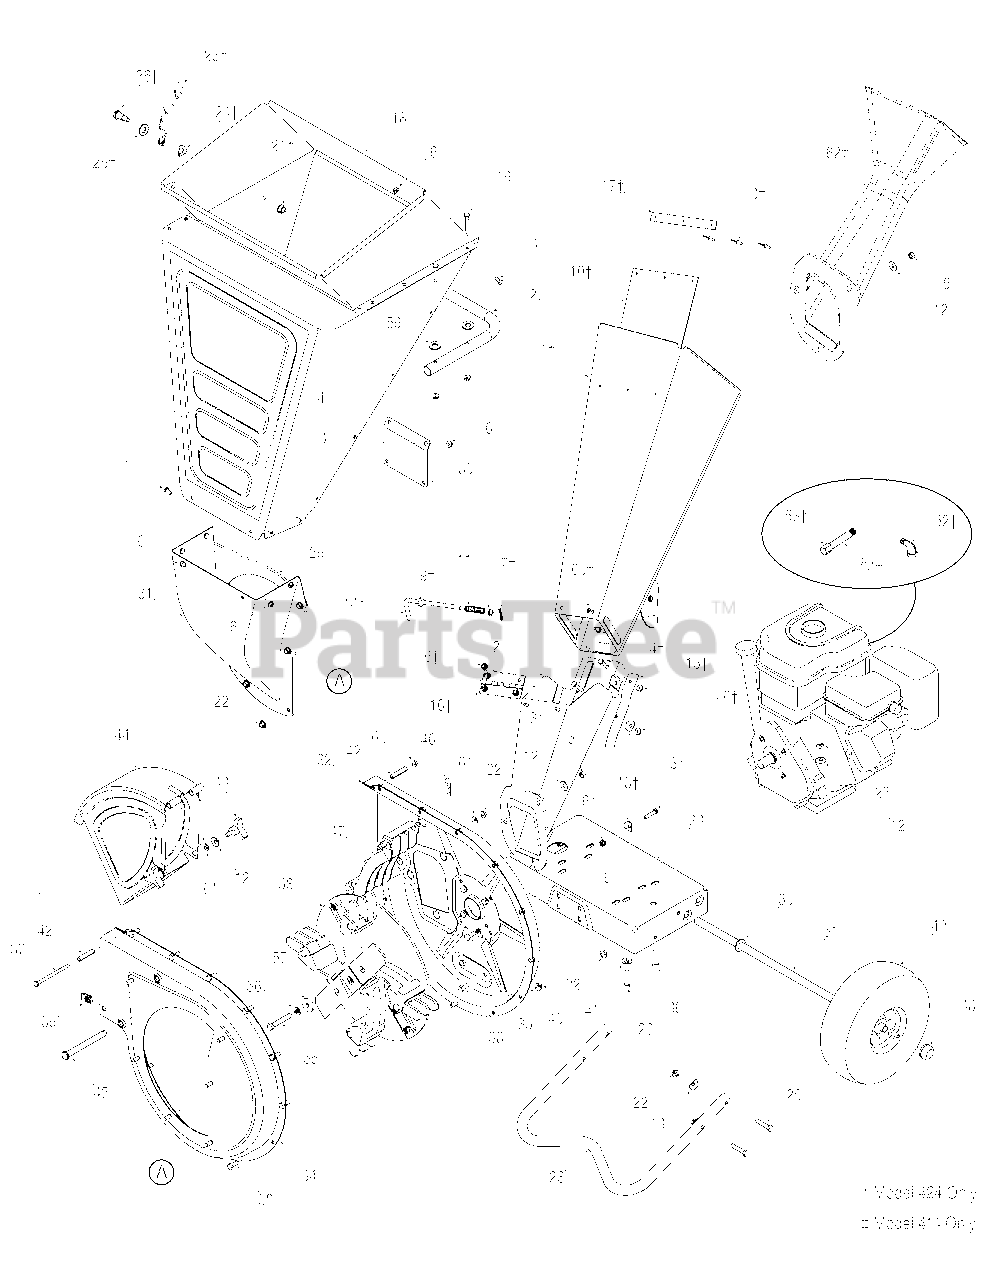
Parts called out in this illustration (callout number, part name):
3	Hex Cap Screw, 1/4-20 x 1.25 (Model 424, CS4210 Only)
4	Hex Cap Screw, 1/4-20 x.5
5	Hex Nut, 5/16-18
6	Hex Lock Nut 1/4-20
7	Cotter Pin (Model 424, CS4210 Only)
8	Pop Rivet (Model 424, CS4210 Only)
9	Compression Spring,.531 x 1.75 (Model 424, CS4210 Only)
10	Chute Flap (Model 424, CS4210 Only)
11	Flat Washer (Model 424, CS4210 Only)
12	Bell Washer.340 ID x.872
13	Washer,.320 ID x.93 OD
14	Lock Rod (Model 424, CS4210 Only)
16	Chipper Chute Hinge (Model 424, CS4210 Only)
17	Chute Flap Strip (Model 424, CS4210 Only)
19	Hex Cap Screw, 1/4-20 x 1.250
20	Hex Cap Screw, 5/16-18 x 1.50
21	Flange Lock Nut, 3/8-16 (Model 424, CS4210 Only)
22	Flange Lock Nut, 5/16-18
23	Torsion Spring (Model 424, CS4210 Only)
24	Spring Washer,.50 x 1.0 x .22 (Model 424, CS4210 Only)
25	Flat Washer,.50 x 1.0 x.0125 (Model 424, CS4210 Only)
26	Shoulder Screw, 3/8-16,.50 x.685 (Model 424, CS4210 Only)
35	Hex Cap Screw, 5/16-24 x.75
36	Hex Sems Screw, 3/8-16 x 1.25
37	Hex Cap Screw, 1/4-20 x 3.75
38	Hex Cap Screw, 5/16-18 x.625
39	U-Nut, 5/16-18
40	Lock Washer, 5/16
41	Special Lock Washer, 5/16
42	Hinge Spacer,.265 x.380 x 1.66
43	Knob Assembly (Incl. ref.# 12 & 61)
45	Clevis Pin,.50 x 4.62
46	Internal Cotter Pin
47	Shredder Screen
48	Push Cap, 5/8
49	Wheel, 10 x 4 x 4
50	Flat Washer,.625 x 1.0
51	Axle, 22.47"
52	Elbow Fitting (Model 414 Only)
53	Oil Drain End Cap (Model 424, CS4210 Only)
54	Oil Drain Pipe (Model 424, CS4210 Only)
55	Hex Cap Screw, 3/8-24 x 2.2
56	Lock Washer, 3/8
57	Flat Washer,.406 x 1.25
58	Impeller Assembly
59	Flat Washer,.28 x.74 x.063
60	Push Nut,.25ID x.50OD (Model 424, CS4210 Only)
61	Speed Nut,.3125ID
